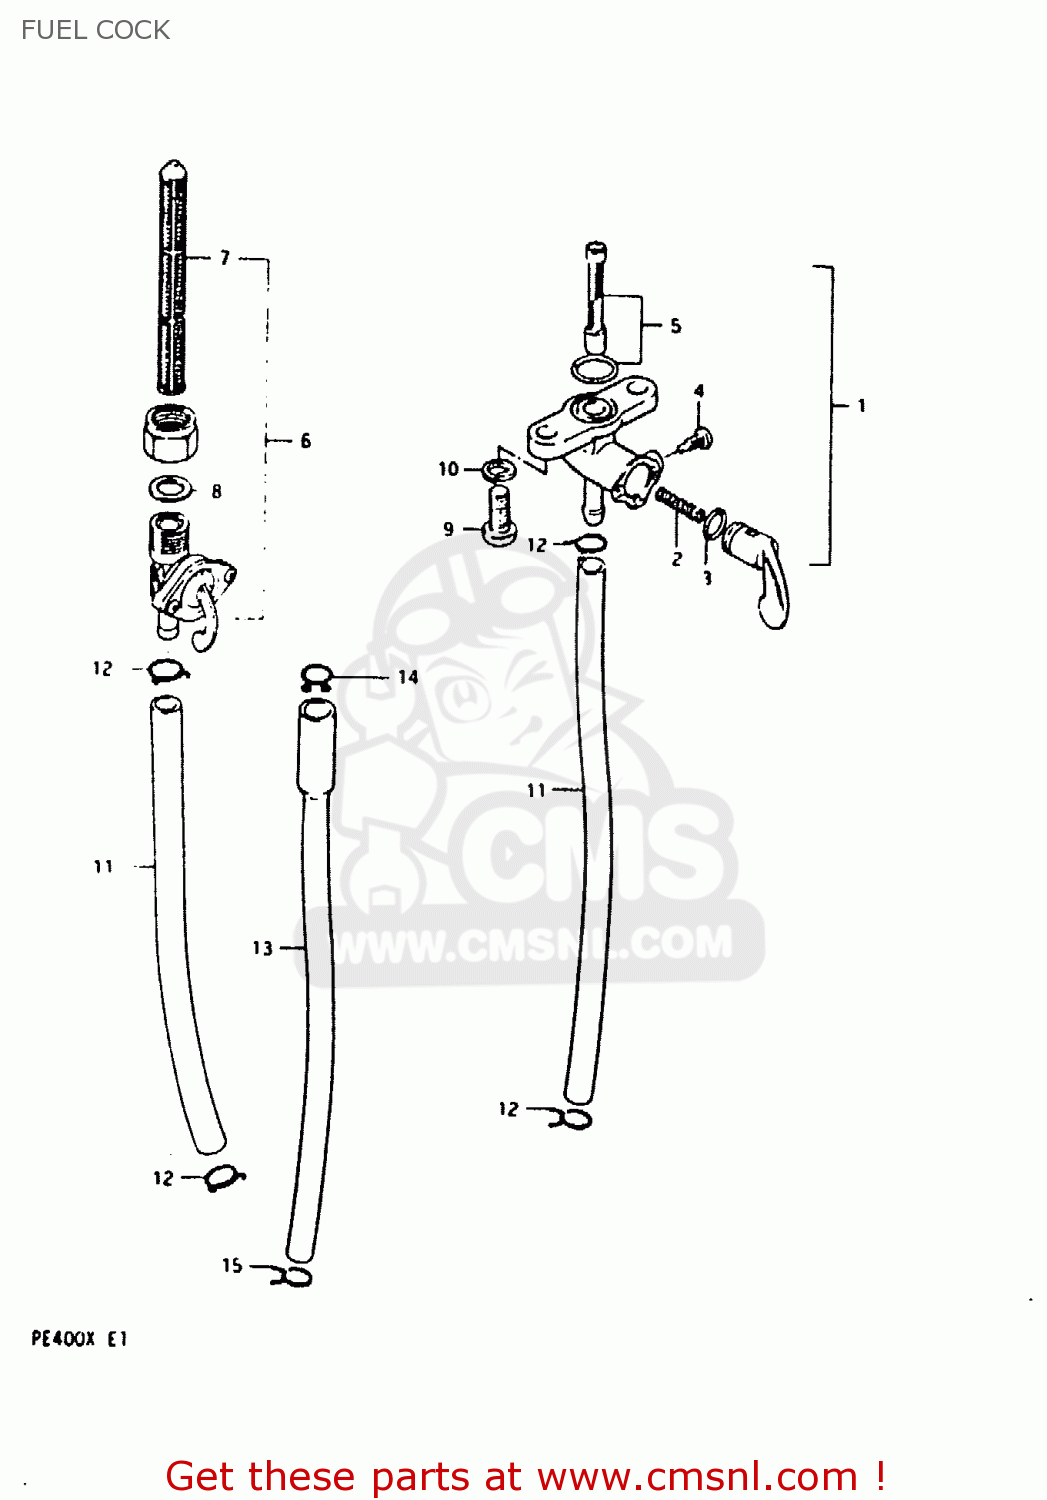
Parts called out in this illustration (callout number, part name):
6	COCK ASSY,FUEL
7	FILTER,FUEL
8	GASKET,FUEL COCK (NAS)
9	SCREW
10	LOCK WASHER
13	HOSE,FUEL
14	CLIP
15	CLAMP
